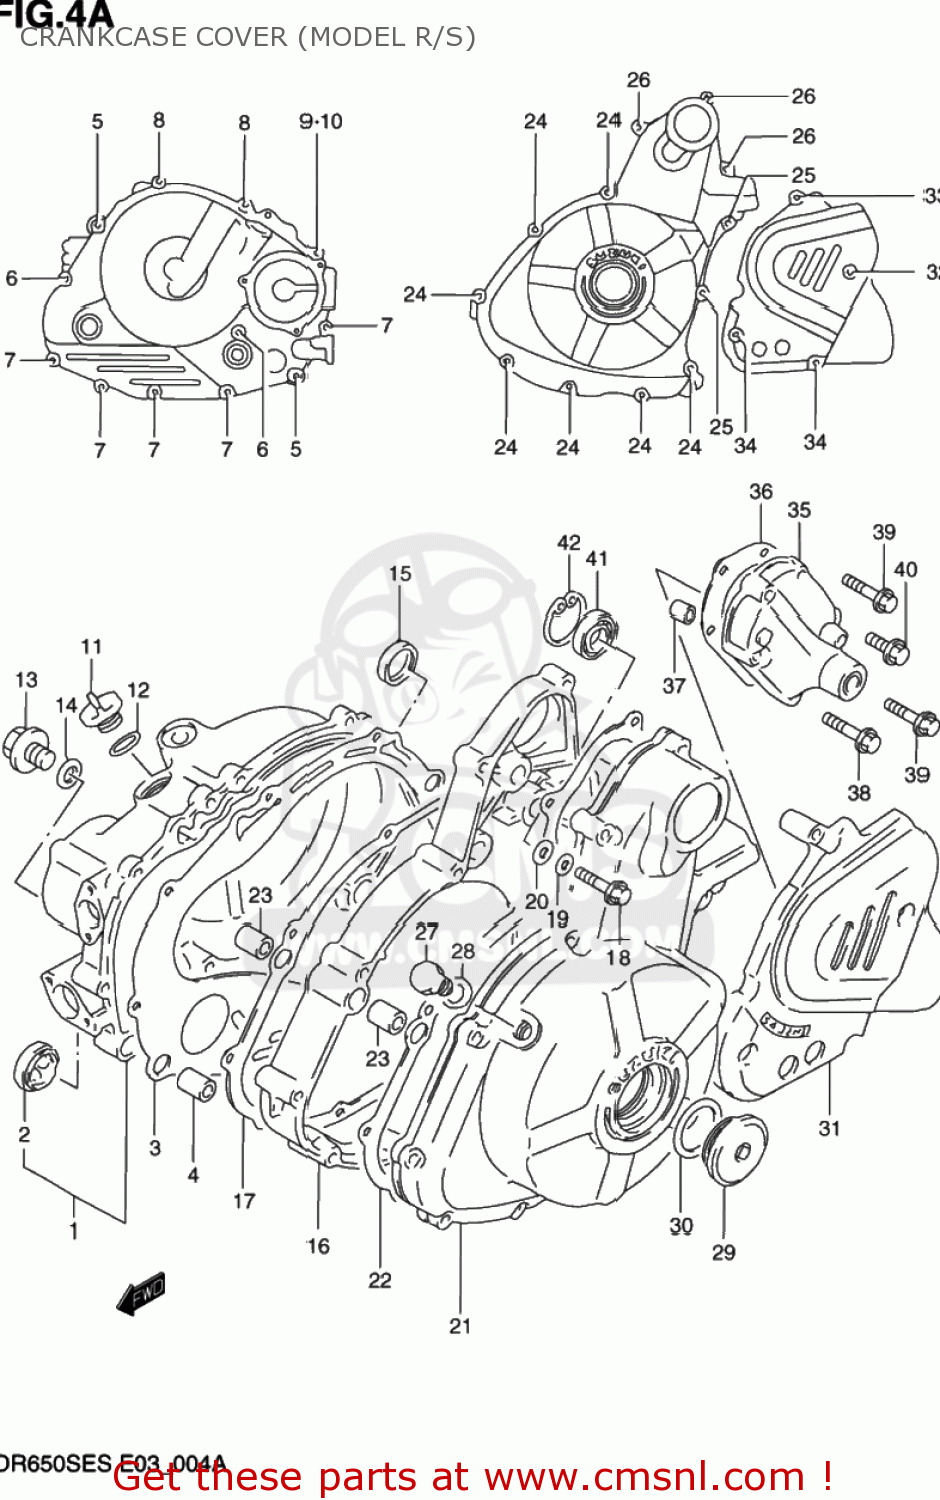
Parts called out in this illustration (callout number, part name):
1	COVER,CLUTCH
2	LENS,OIL LEVEL CHECK
3	GASKET,CLUTCH COVER (NAS)
4	PIN
5	BOLT
6	BOLT
7	BOLT
8	BOLT
9	BOLT(6X25)
10	WASHER
11	PLUG
12	O RING(D:3.1,ID:16.8)
13	PLUG(14X12)
14	GASKET(13.8X18.8X4.8) (NAS)
15	PLUG,CLUTCH COVER KICK
16	COVER,GENERATOR,INNER
17	GASKET,MAGNETO COVER (NAS)
18	BOLT,G/S SWITC
19	LOCK WASHER
20	WASHER
21	COVER,GENERATOR OUTER
22	GASKET,GENERATOR OUTER COVER (NAS)
23	PIN
24	BOLT
25	BOLT
26	BOLT
27	PLUG(12X9)
28	GASKET(12.1X16.2X3.7) (NAS)
29	PLUG(SILVER)
30	O RING(D:3.1,ID:32.7)
31	COVER,ENGINE SPROCKET
32	BOLT
33	BOLT
34	BOLT
35	COVER,GEAR SHIFT
36	GASKET,GEAR SHIFT COVER (NAS)
37	PIN
38	BOLT
39	BOLT,G/S SWITC
40	SCREW
41	BEARING(12X28X8)
42	CIRCLIP
